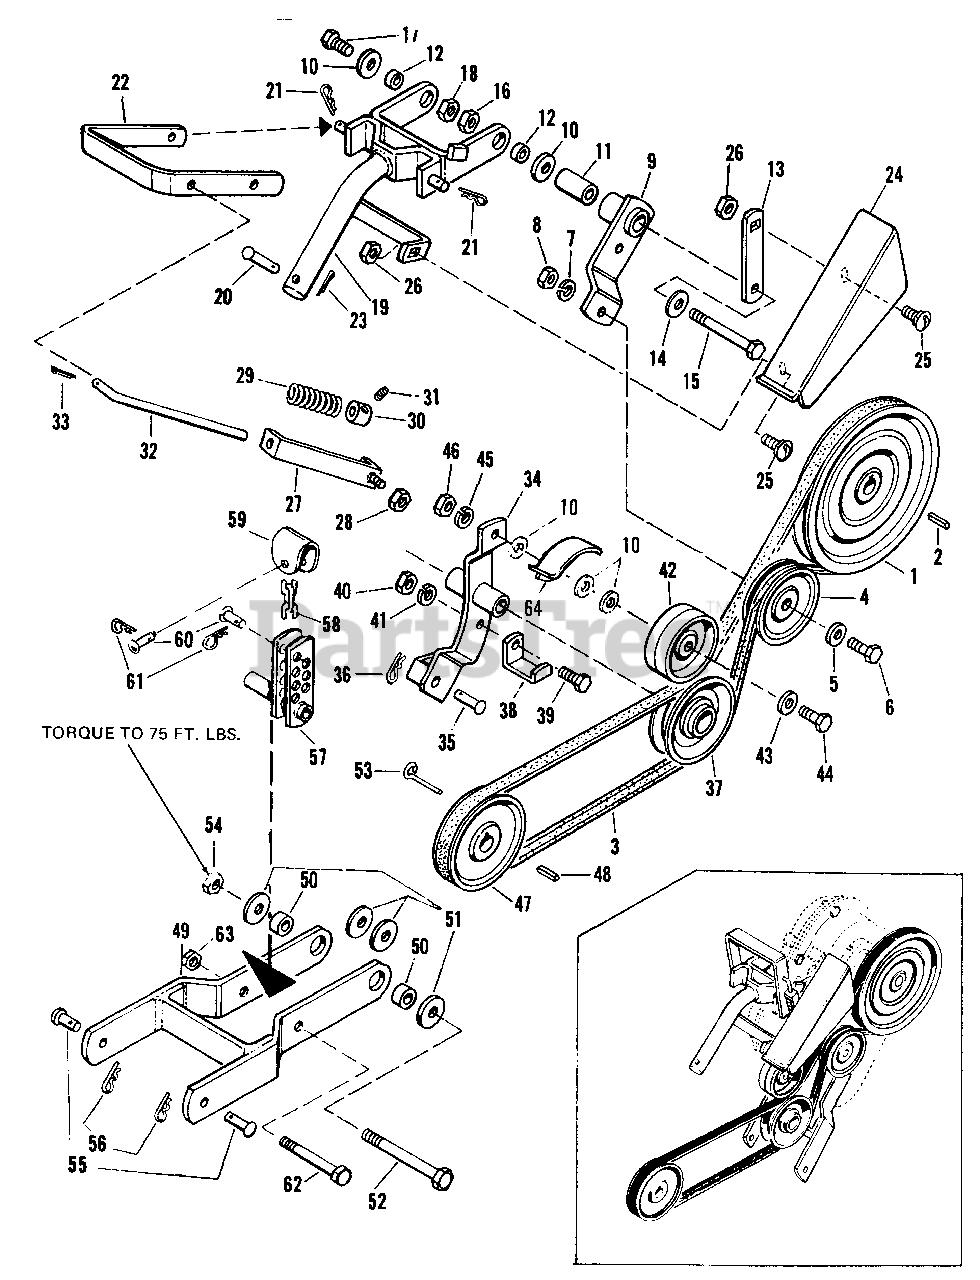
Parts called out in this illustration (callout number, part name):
3	"V" Belt, Sovereign Tractor
5	Plain Washer, 5/16"
6	Hex. Capscrew, 3/8"-16 x 1-1/4"
7	Lock Washer, 3/8"
8	Full Hex. Nut, 3/8"-16
9	Clutch Lever Assembly
10	Plain Washer, 3/8"
13	Rear Support Belt Guard
14	Plain Washer, 7/16"
15	Hex. Capscrew, Gr. 8, 7/16"-14 x 3-1/2"
16	Flange Locknut, 7/16-14
17	Hex. Capscrew, Gr. 8, 7/16"-14 x 1-1/4"
18	Flange Locknut, 7/16-14
19	Lift Bar Assembly
20	Pin
21	Spring Clip
22	Clutch Handle
23	Cotter Pin, 3/32" x 3/4"
24	Belt Guard
25	Carriage Bolt, 5/16"-18 x 1/2"
26	Nut Whiz Lock, 5/16"-18
27	Rod Guide Assembly
28	Full Hex. Nut Lock, 5/16"-18
31	Cup Pt. Sq. Hd. Setscrew, 1/4"-20 x 3/8"
32	Clutch Rod
33	Cotter Pin, 3/32" x 3/4"
34	Arm Idler Assembly
36	Spring Clip
37	Idler Pulley
38	Belt Guard, 1/8 x 1 x 4-1/8"
39	Hex. Capscrew, 3/8"-16 x 7/8"
40	Full Hex. Nut, 3/8"-16
41	Lock Washer, 3/8"
42	Idler Pulley
43	Plain Washer, 5/16"
44	Hex. Capscrew, 3/8"-16 x 1-3/4"
45	Lock Washer, 3/8"
46	Full Hex Nut, 3/8"-16
49	Frame Assembly
51	Plain Washer, 1/2"
52	Hex Capscrew, 1/2"-13 x 5"
53	Belt Stop Gr. 8
54	Full Hex. Locknut, 1/2"-13 N.C.
56	Spring Clip
57	Depth Limit Bracket Assy.
58	Chain
59	Chain Clip
61	Spring Clip
62	Hex. Capscrew, 3/8"-16 x 4-1/2"
63	Hex. Nut, Full Lock, 3/8-16 x 1-3/4
64	Guard Assembly
